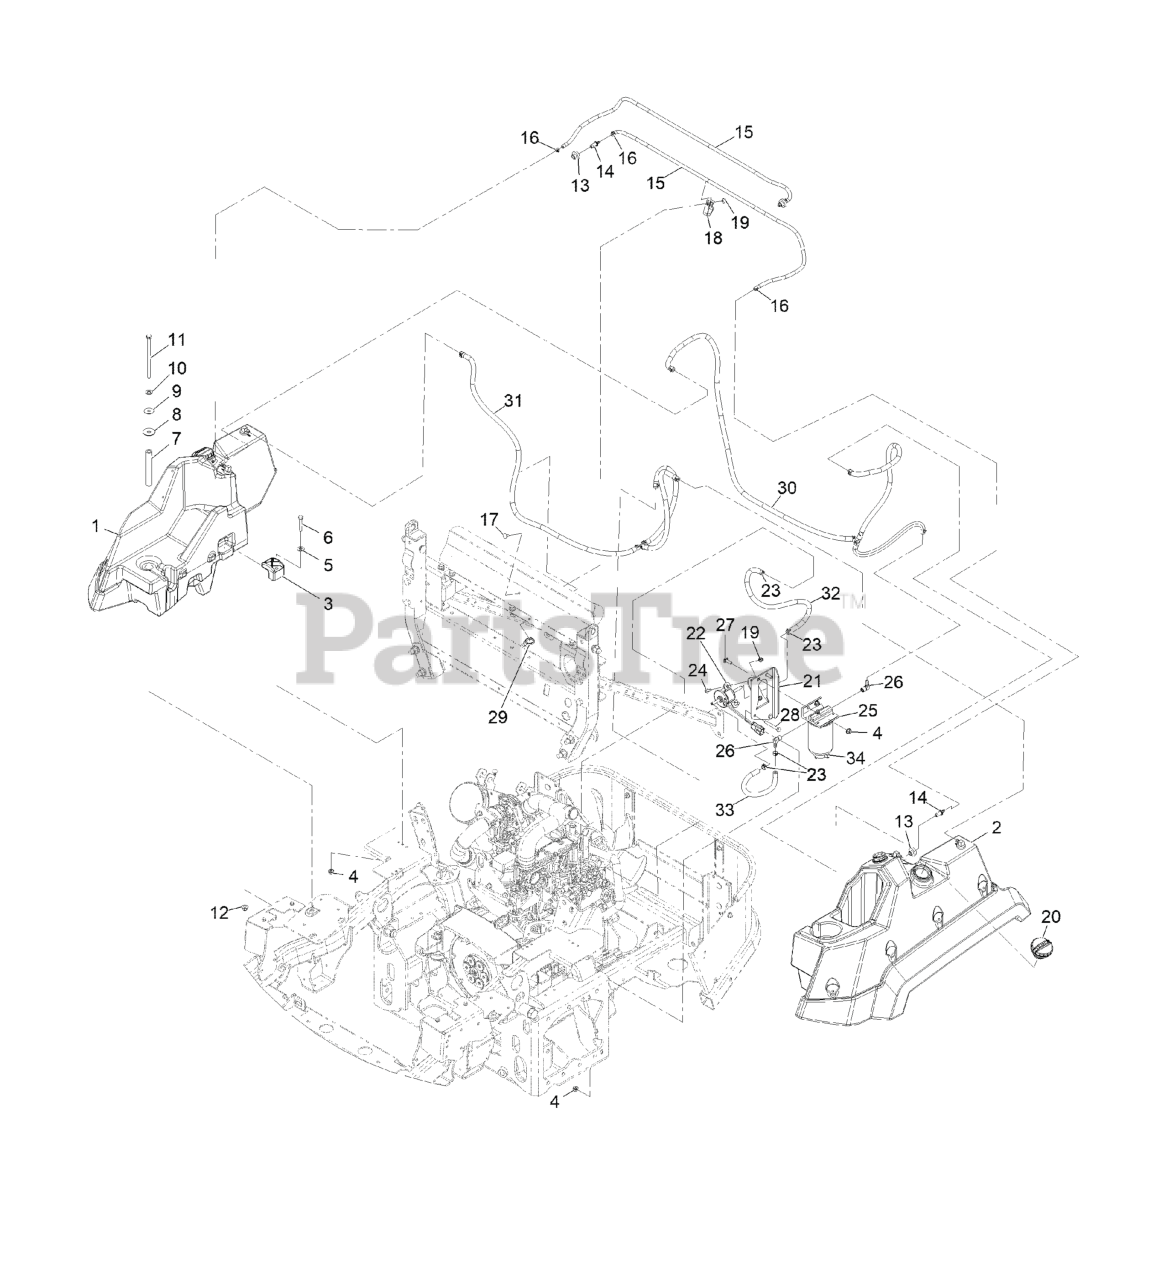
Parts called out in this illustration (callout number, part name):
1	RH FUEL TANK ASM
2	LH FUEL TANK ASM
4	NUT-HF, NI
5	WASHER-FLAT
6	SCREW-HH
7	TUBE-SPACER
8	WASHER-RUBBER
9	WASHER-PLAIN
10	WASHER-FLAT
11	SCREW-HH
12	NUT-HF, NI
13	BUSHING
14	FITTING-ORIFICE, STRAIGHT
15	HOSE-VENT, TANK
16	CLAMP-HOSE
17	SCREW-CARR
18	CLAMP-HOSE
20	CAP-FUEL, DIESEL
21	BRACKET-FILTER AND PUMP,
22	PUMP-FUEL, ELECTRIC
23	CLAMP-HOSE
24	SCREW-HWH
25	ASM,FUEL FILTER W/HEAD
26	FITTING-HYD, 90
27	SCREW-CARR
28	SCREW-HH
29	CLIP-TIE
30	LINE-FUEL, SUCTION
31	LINE-FUEL, RETURN
32	HOSE-FUEL
33	HOSE-FUEL
34	FILTER-FUEL
